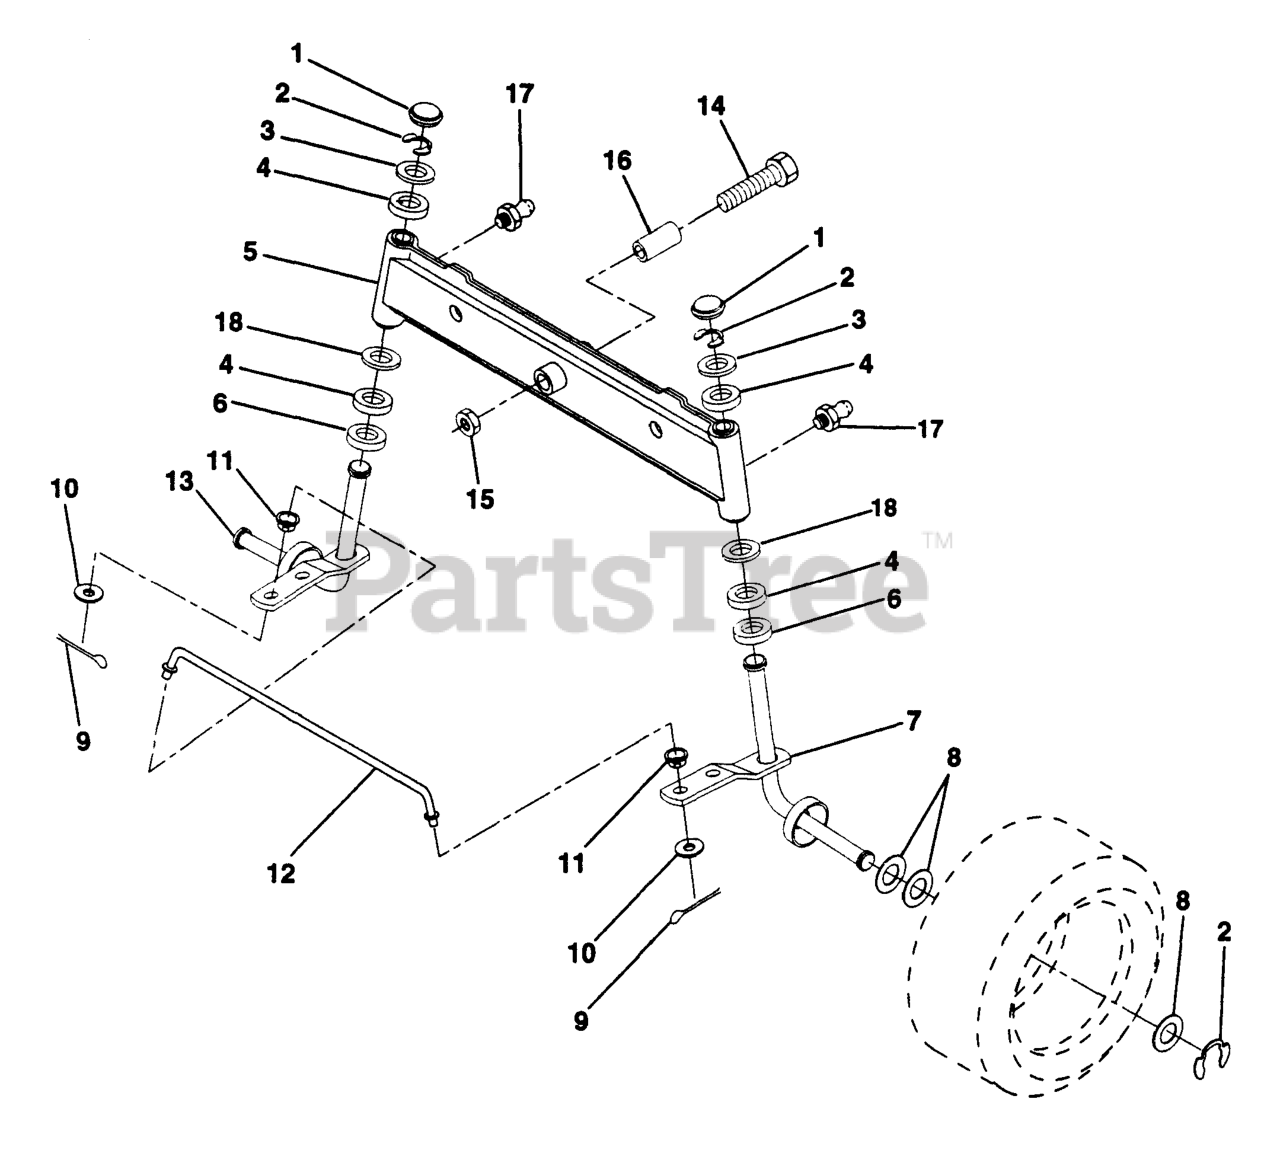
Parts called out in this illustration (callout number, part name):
1	CAP.SPINDLE.BLACK
4	BRNG T
6	THRUST WASHER
7	SPINDLE ASSY RH NLA
9	COTTER PIN
10	WASHER
11	BUSHING.DRAGLINK (2 2)
12	TIE ROD
13	SPINDLE ASSY LH
14	Bolt Hex 5/8-11 Unc x 3-1/2
15	NUT-LOC,FLANGE LT
16	BEARING
17	ZERK M
